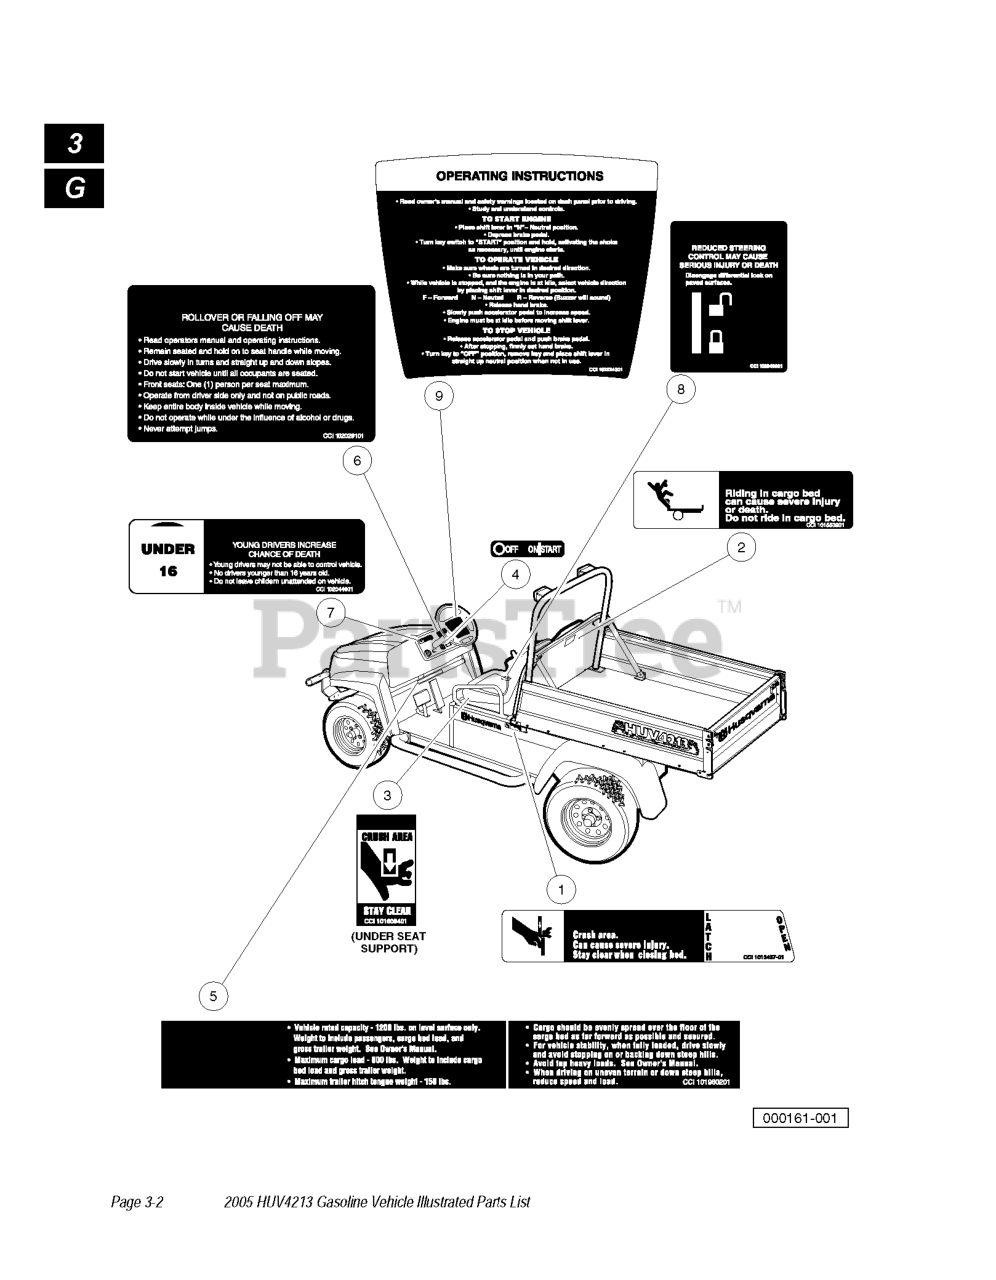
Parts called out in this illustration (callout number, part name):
1	DECAL, TILT BED WARNING
2	DECAL, BED LOAD WARNING
3	DECAL, CRUSH AREA WARNING
4	DECAL, IGNITION-350 ENGINE
5	DECAL, VEHICLE LOADING
6	DECAL, DASH WARNING
7	UNDERAGE WARNING DECAL
8	DECAL, DIFF LOCK WARNING
9	DECAL OPER INSTR KEY START
